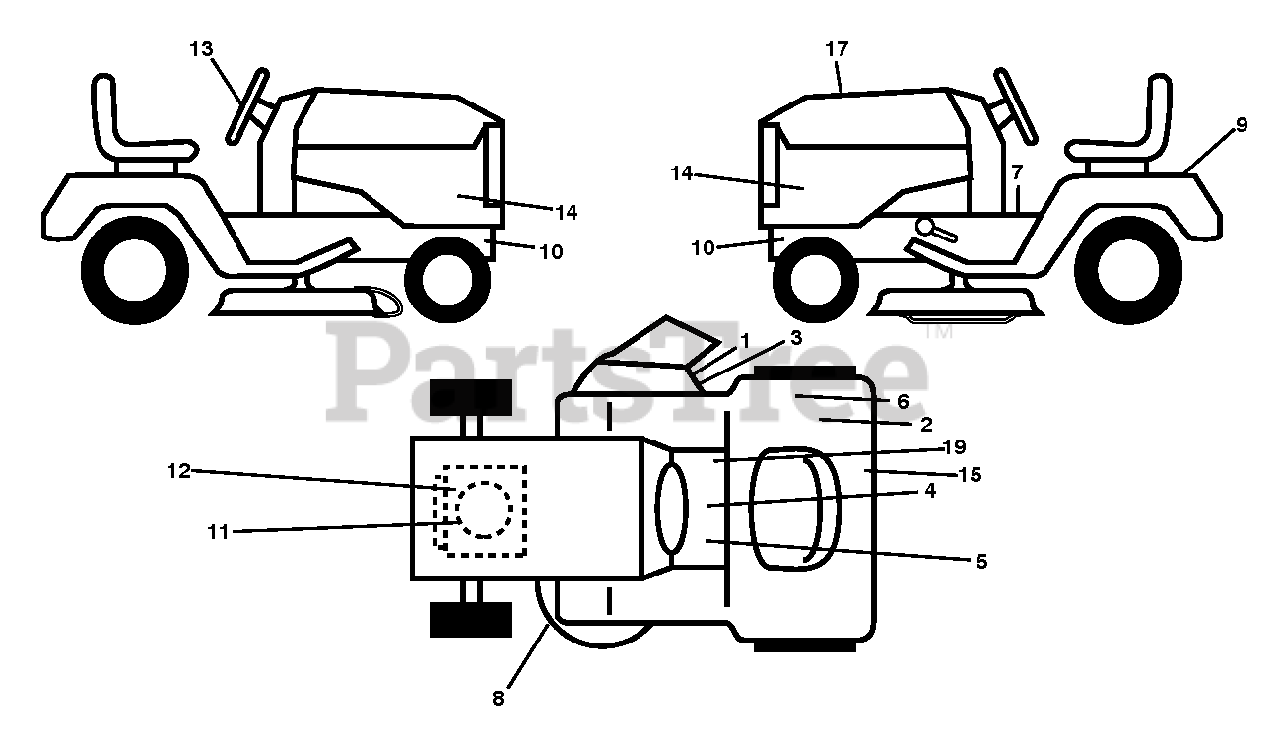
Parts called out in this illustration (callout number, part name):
1	DECAL.INTERNATIONL.CUTFINGER
3	DECAL, DEFLECT WARNING
4	DECAL PARK BRAKE
6	DECAL.80 DBA.AUSTRALIA
8	DECAL V BELT SCHEMATIC
9	DECAL BTRY SYMBOLS
